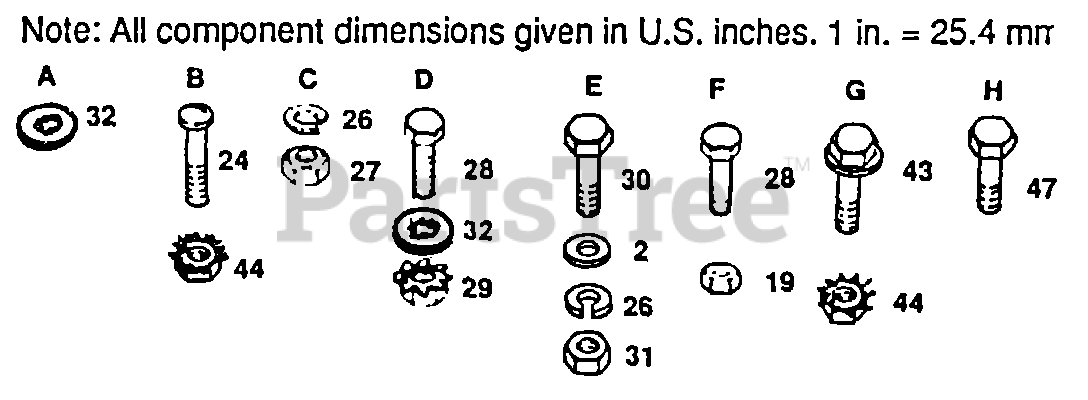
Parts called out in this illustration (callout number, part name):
2	WASHER
26	LOCKWASHER
27	NUT
28	BOLT
29	NUT
30	BOLT LT
43	SCREW
44	"NUT,KEPS"
47	SCREW
